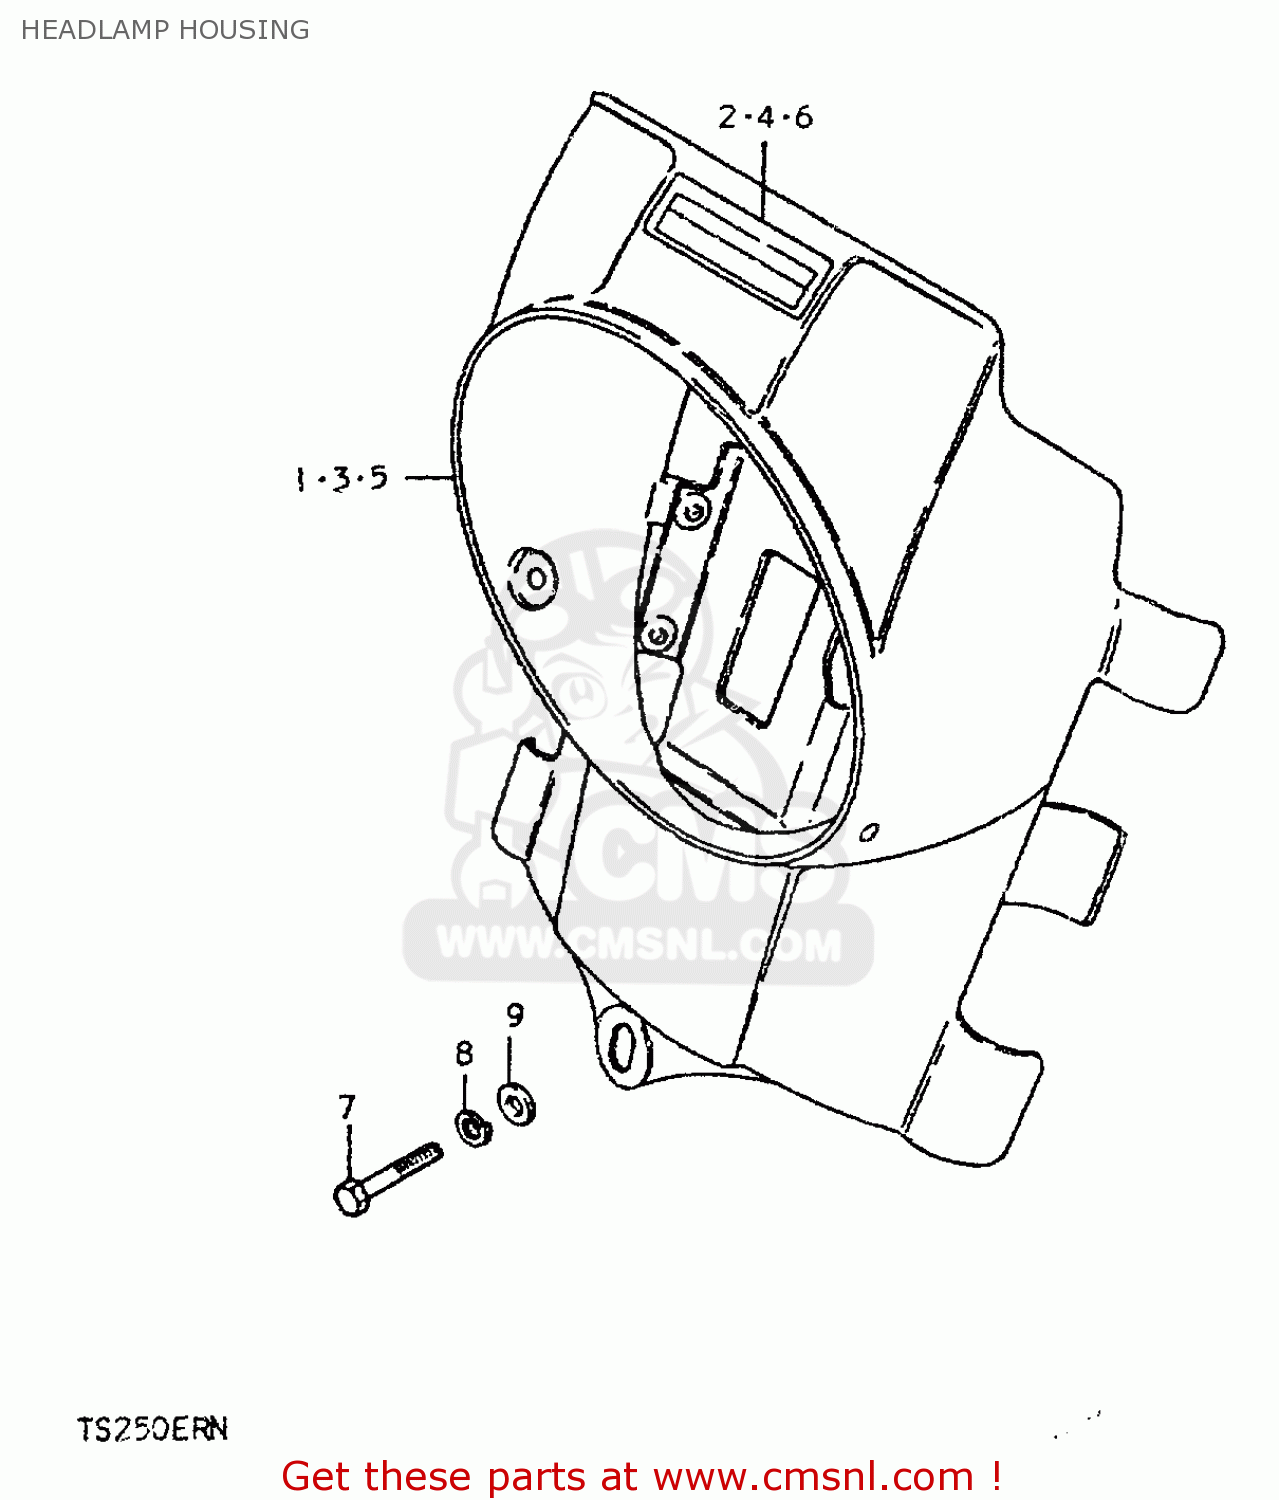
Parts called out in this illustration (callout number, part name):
1	HOUSING, HEADLAMP
2	TAPE, HOUSING
3	HOUSING, HEADLAMP
4	TAPE, HOUSING
5	HOUSING, HEAD LAMP
6	TAPE, HOUSING
7	BOLT
8	LOCK WASHER
9	WASHER
